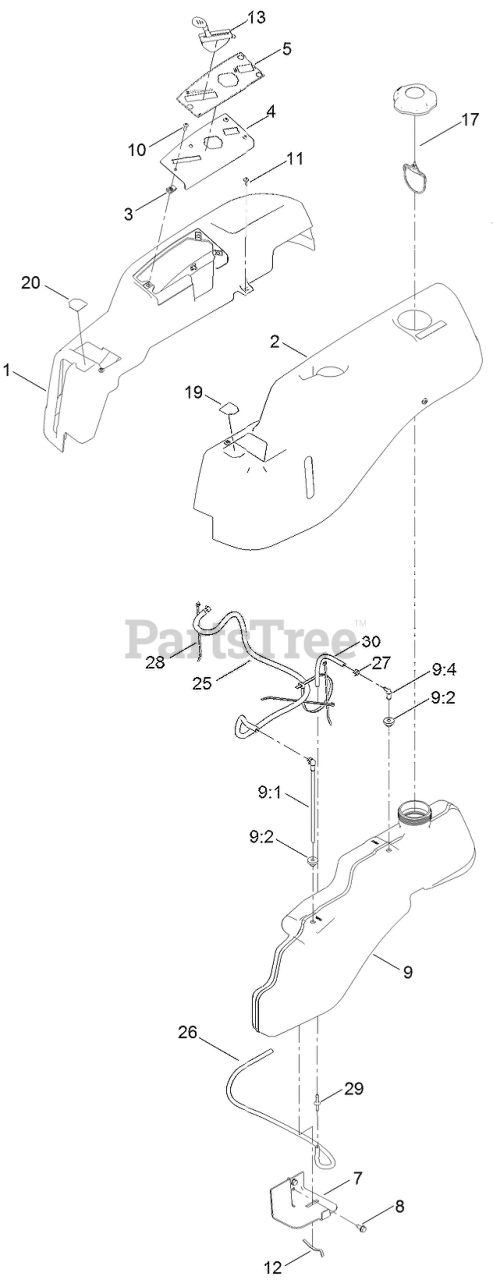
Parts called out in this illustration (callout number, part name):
1	POD-RH
2	POD-LH
4	PLATE-CONTROL
5	DECAL-PANEL, CONTROL
7	SUPPORT-TANK, FRONT
8	SCREW-HWHTF
9	FUEL TANK ASM
9:1	CONNECTOR-ELBOW, 90 DEG
9:2	BUSHING
9:4	FITTING-PLASTIC
10	SCREW-PRH
11	SCREW-SHOULDER
12	SPRING
13	CABLE-THROTTLE AND CHOKE
17	CAP-FUEL, RATCHETING
19	DECAL-LEVER, CONTROL (LH)
20	DECAL-LEVER, CONTROL (RH)
25	HOSE-FUEL
26	HOSE-FUEL
27	CLAMP-HOSE
28	TIE-CABLE
29	ADAPTOR-ORIFICE
30	HOSE-FUEL
